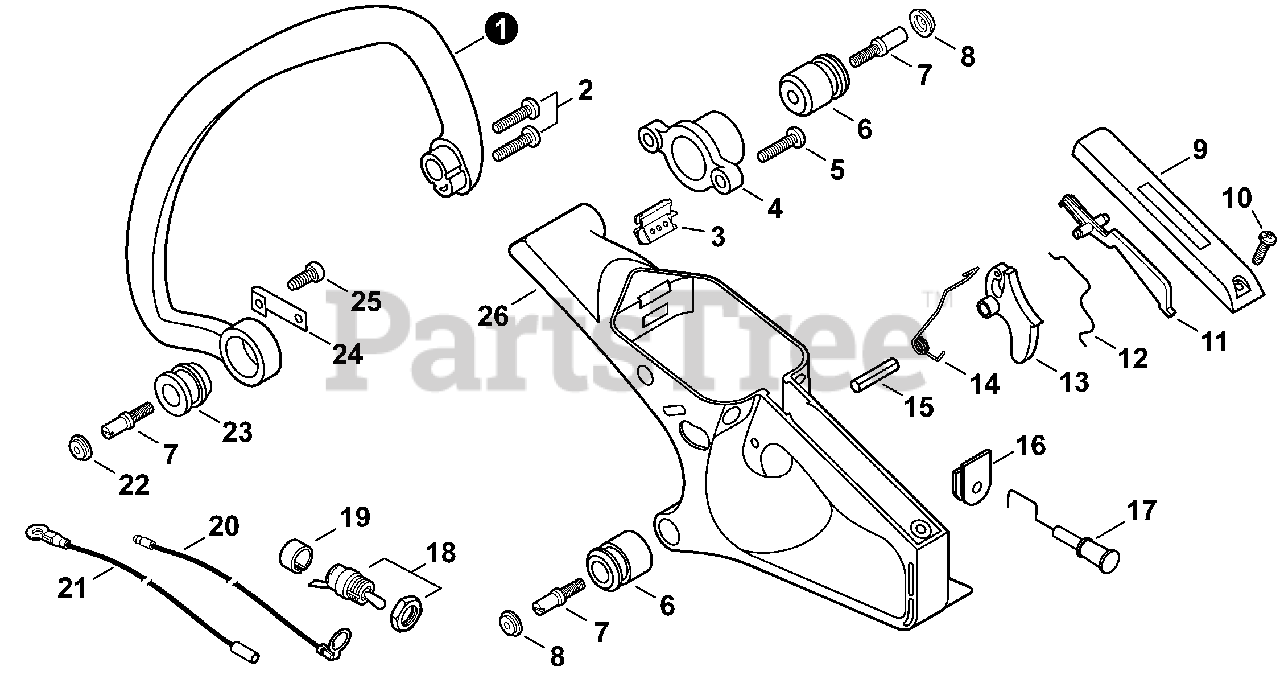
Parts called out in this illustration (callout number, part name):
1	HANDLE, FRONT
2	SCREW 5×20
3	GROMMET, DUST
4	BRACKET, CUSHION
5	SCREW 4×16
6	CUSHION 4
7	BOLT 4×15
8	CAP, CUSHION
9	COVER, HANDLE
10	SCREW 4×12
11	LEVER, THROTTLE LOCKOUT
12	ROD, THROTTLE
13	TRIGGER, THROTTLE
14	SPRING, TORSION
15	PIN, SPRING 4×25 SUS
16	GROMMET, CHOKE
17	KNOB, CHOKE
18	SWITCH, ON-OFF
19	CAP, SWITCH
20	LEAD - GROUND L220
21	LEAD - GROUND L170
22	CAP, CUSHION
23	CUSHION 5
24	STOPPER
25	SCREW 4×8
26	HANDLE, REAR
